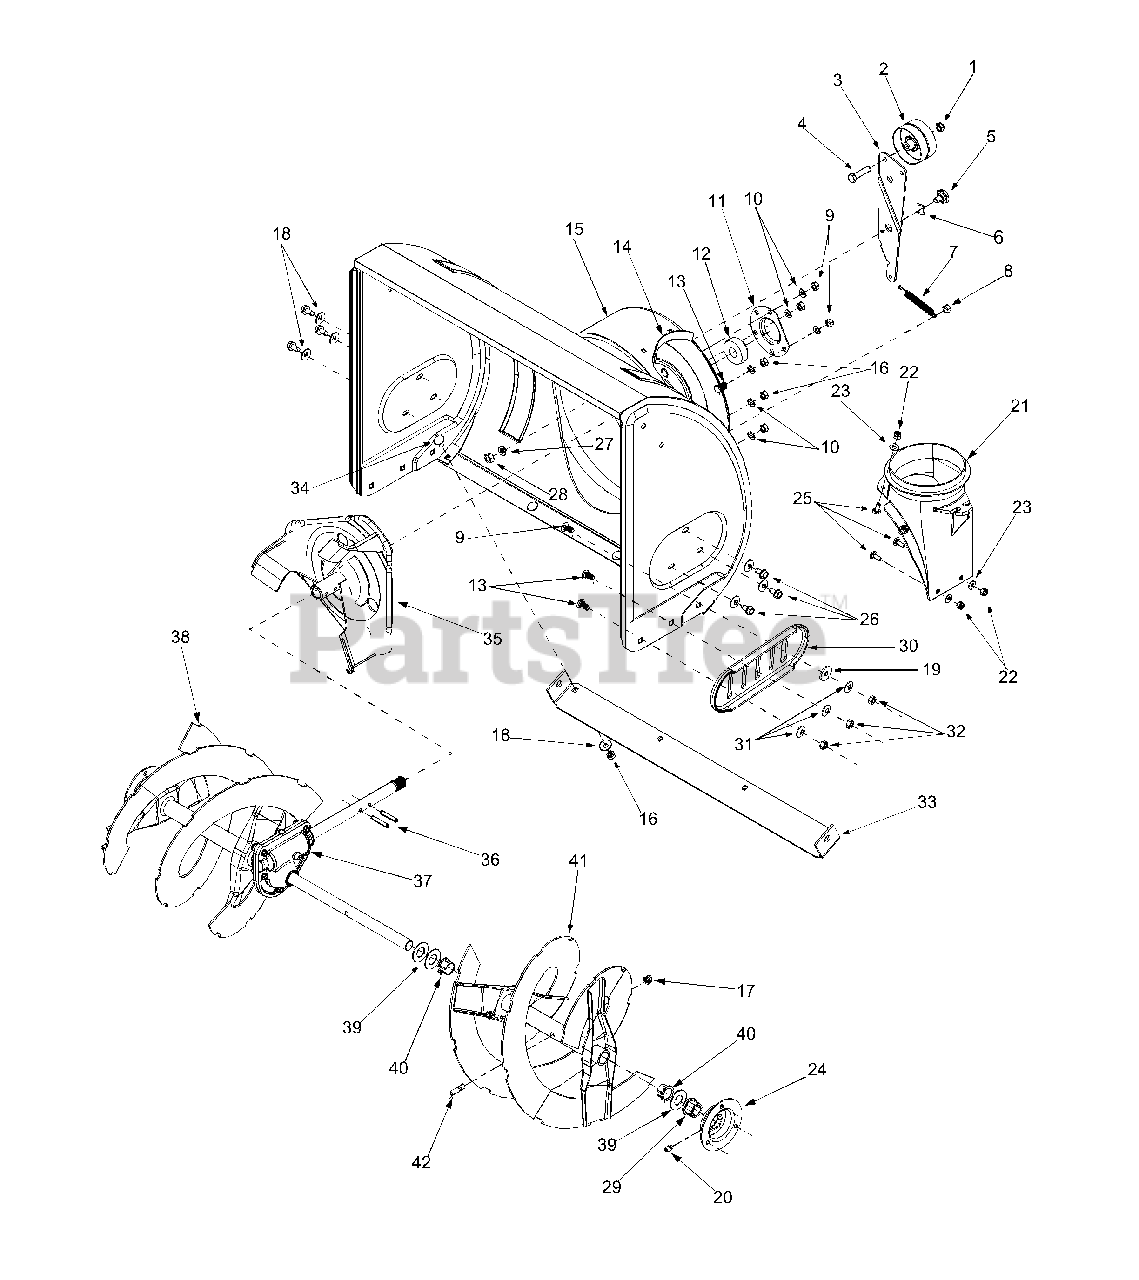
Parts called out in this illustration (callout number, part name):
1	Lock Jam Nut 3/8-24
4	Hex Cap Screw 3/8-24 x 1.50
5	Shoulder Screw
6	Wave Washer
7	Extension Spring
8	Hex Nut 5/16-18
9	Carriage Bolt, 5/16-18 x 1.00
10	Lock Washer 5/16
12	Ball Bearing
13	Carriage Bolt, 5/16-18 x .75
17	Lock Nut 5/16-18
18	Belleville Washer
19	Flat Wshr, .344ID x 1.125 OD
20	Grease Fitting, 3/16" Drive
21	Chute Adapter
22	Hex Lock Nut 1/4-20
24	Bearing Housing w/Fitting
25	Carriage Screw 1/4-20 x .75
26	Hex Screw 5/16-18
27	Lock Washer 3/8
28	Hex Nut 3/8-16
29	Hex Flange Bearing
32	Hex Nut 5/16-18
34	Carriage Bolt 5/16-18 x .62
37	26" Gear Ass'y (850W)
40	Flange Bushing
